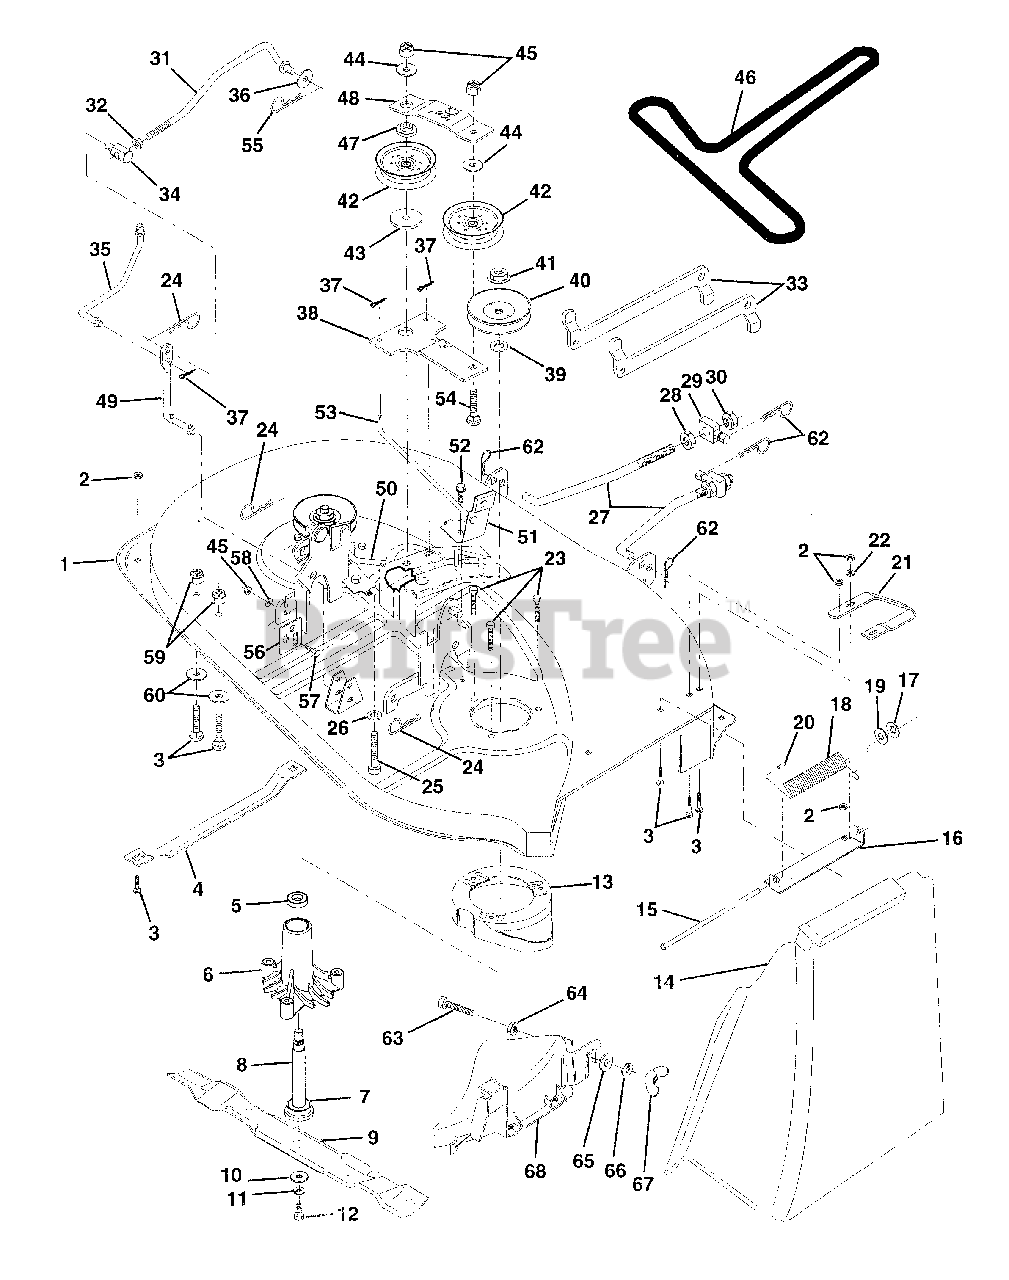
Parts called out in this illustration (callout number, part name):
1	Mower Deck Assembly
2	Nut, Crownlock 5/16-18
3	Bolt, Carriage 5/16-18 x 3/4
4	Runner, L.H.
6	Housing, Mandrel
8	Shaft and Bearing Assembly, Man
9	Blade, Mulching
10	Washer, Hardened
11	Washer, Lock 3/8
12	Bolt, Hex 3/8-24 x 1-1/4 Grade 8
13	Stripper, Mower, Vented
14	Shield, Deflector
15	Rod, Hinge
16	Bracket Assembly, Deflector
18	Spring, Deflector
19	Washer 11/32 x 5/8 x 16 Gauge
20	Cap, Sleeve
21	Runner, R.H.
22	Washer 11/32 x 3/4 x 16 Gauge
23	Bolt, Hex Head 5/16-18 x 1-1/4
24	Retainer, Spring
25	Bolt, Carriage 3/8-16 x 2-1/4
26	Washer 13/32 x 1 x 12 Gauge
27	Link Assembly, Front
28	Nut, Hex, Jam 1/2-13 UNC
29	Trunnion
30	Locknut with Washer Insert 1/2-13 UNC
31	Clutch Rod, Primary
32	Nut, Hex, Jam 3/8-16
33	Arm, Suspension, Rear
34	Trunnion 3/8-16
35	Clutch Rod, Secondary
36	Washer 13/32 x 13/16 x 16 Gauge
37	Pin, Cotter 3/32 x 3/4
38	Idler Arm
39	Washer .150 Thick
40	Pulley, Mandrel
41	Nut, Flangelock 9/16
42	Pulley, Flat Idler
43	Spacer, Retainer
44	Washer 13/32 x 1 x 12 Gauge
45	Nut, Crownlock 3/8-16
46	Belt
47	Spacer, Idler Arm
48	Stiffener, Idler Arm
49	Rod, Pivot
50	Rod, Brake, L.H.
51	Brake Assembly
52	Screw, Hex Washer Head, Thd., Roll. 5/16-18 x 3/4
53	Rod, Brake, R. H.
54	Bolt, Carriage 3/8-16 x 1-3/4 Grade 5
55	Spring, Retainer
56	Plate, Adjustment, Rear Link, L.H.
57	Bolt, Carriage 3/8-16 x 3/4
58	Washer 13/32 x 3/4 x 12 Gauge
59	Locknut, Hex, with Washer Insert 5/16-18
60	Washer 11/32 x 11/16 x 12 Gauge
62	Retainer, Spring
63	Bolt, Hex Head 3/8-16 x 1-1/4
64	Locknut 3/8-16
65	Washer 13/32 x 1-1/4 x 16 Gauge
66	Washer, Lock, Heavy Helical Spring 3/8
68	Cover Assembly, Mulching
68	Mandrel Assembly
68	Mower Deck,
